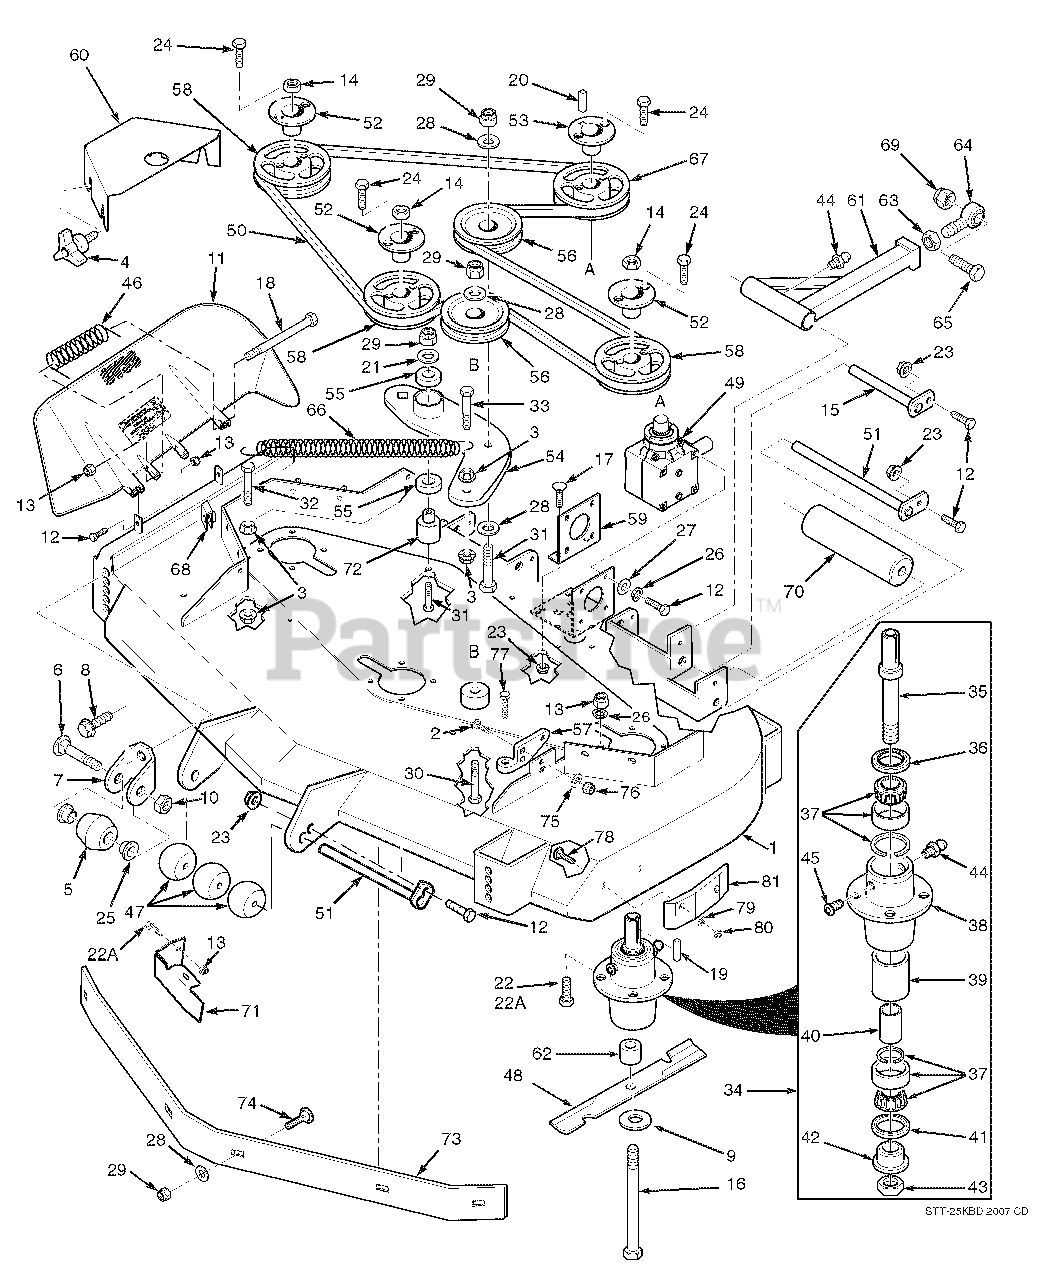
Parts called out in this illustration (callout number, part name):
1	Cutter Deck Velocity Plus
2	Bolt, Carriage 7/16-14 x 1-1/4"
3	Nut, Hex Serrated Flange 3/8-16
4	Wing nut, 3/8-16
5	Anti-Scalp Wheel
6	Bolt, Carriage 3/8-16 x 4"
7	Anti-Scalp Wheel Bracket
8	Bolt, Hex Serrated Flange 3/8-16 x 1"
9	Flatwasher, 5/8" Hardened
10	Locknut, 3/8-16 Center Lock
11	Discharge Chute
12	Bolt, Hex Head 5/16-18 x 1-3/4" - Front
13	Nut, Hex Elastic Stop 5/16-18 Grade 8
14	Nut, 5/8-11 UNC
15	Push Arm Shaft
16	Bolt, Hex Head 5/8-11 x 9-1/2"
17	Bolt, Carriage 5/16-18 x 3/4"
18	Bolt, Hex Head 5/16-18 x 4-1/2"
19	Key, 1/4 x 1/4 x 2"
20	Key, 1/4 x 1/4 x 1-1/4"
21	Flatwasher,3/8-.39 x .938 x .105 HD
22	Bolt, Hex Head 5/16-18 x 1-3/4"
23	Nut, Hex Serrated Flange 5/16-18
24	Bolt, Hex Head 1/4-20 x 1” Grade 8
25	Bushing, .376 I.D. Oilite
26	Lockwasher, 5/16"
27	Flatwasher, 5/16"
28	Flatwasher, 3/8"
29	Nut, Hex Elastic Stop 3/8-16
30	Bolt, Hex Head 3/8-16 x 3-1/4"
31	Bolt, Hex Head 3/8-16 x 3"
32	Bolt, Hex Head 3/8-16 x 1-1/2"
33	Bolt, Hex Head 3/8-16 x 1-1/2" Grade 8
34	Spindle Assembly
35	Spindle Shaft
36	Seal, Top
37	Bearing Assembly
38	Spindle Housing
39	Spacer, Outside
40	Spacer, Inside
41	Seal, Bottom
42	Spindle Bushing, Bottom
43	Nut, Special 1 - 1/16-18
44	Grease Fitting
45	Relief Fitting, Tapered Spindle
46	Spring, Discharge Chute
47	Wheel, Anti-Scalp
48	Cutter Blade, 21"
49	Gearbox Assembly, Deck Drive
50	Belt, Cutter Deck Drive
51	Roller Shaft
52	Tapered Hub, 1-1/8" Bore
53	Tapered Hub, 1" Bore
54	Idler Arm, Cutter Deck
55	Bearings, Ball
56	Pulley, Idler
57	Lever Assembly, Deck Level
58	Pulley, 6.35 O.D.
59	Mounting Plate, Gearbox
60	Belt, Cover
61	Pusharm
62	Spacer, Spindle Bottom
63	Nut, Hex Head 5/8-18 UNF
64	Rod End, 5/8" Male RH Thread
65	Bolt, Hex Head 5/8-11 x 4-1/2"
66	Spring, Cutter Deck
67	Pulley, 6.75 O.D.
68	U-Nut, 3/8-16
69	Nut, Hex Elastic Stop 5/8-11
70	Wheel, Anti-Scalp
71	Discharge Baffle 61V
72	Pivot, Idler - Short
73	Baffle, Custom Cut 61V
74	Bolt, Carriage 3/8-16 x 1”
75	Flatwasher, 7/16-.500 x 1.25 x .083
76	Nut, Elastic Stop 7/16-14
77	Bolt, Deck Adjust
78	Bolt, Carraige 5/16-18 x 3/4”
79	Flatwasher, 5/16”
80	Nut, Center Lock 5/16-18
81	Wear Pad
